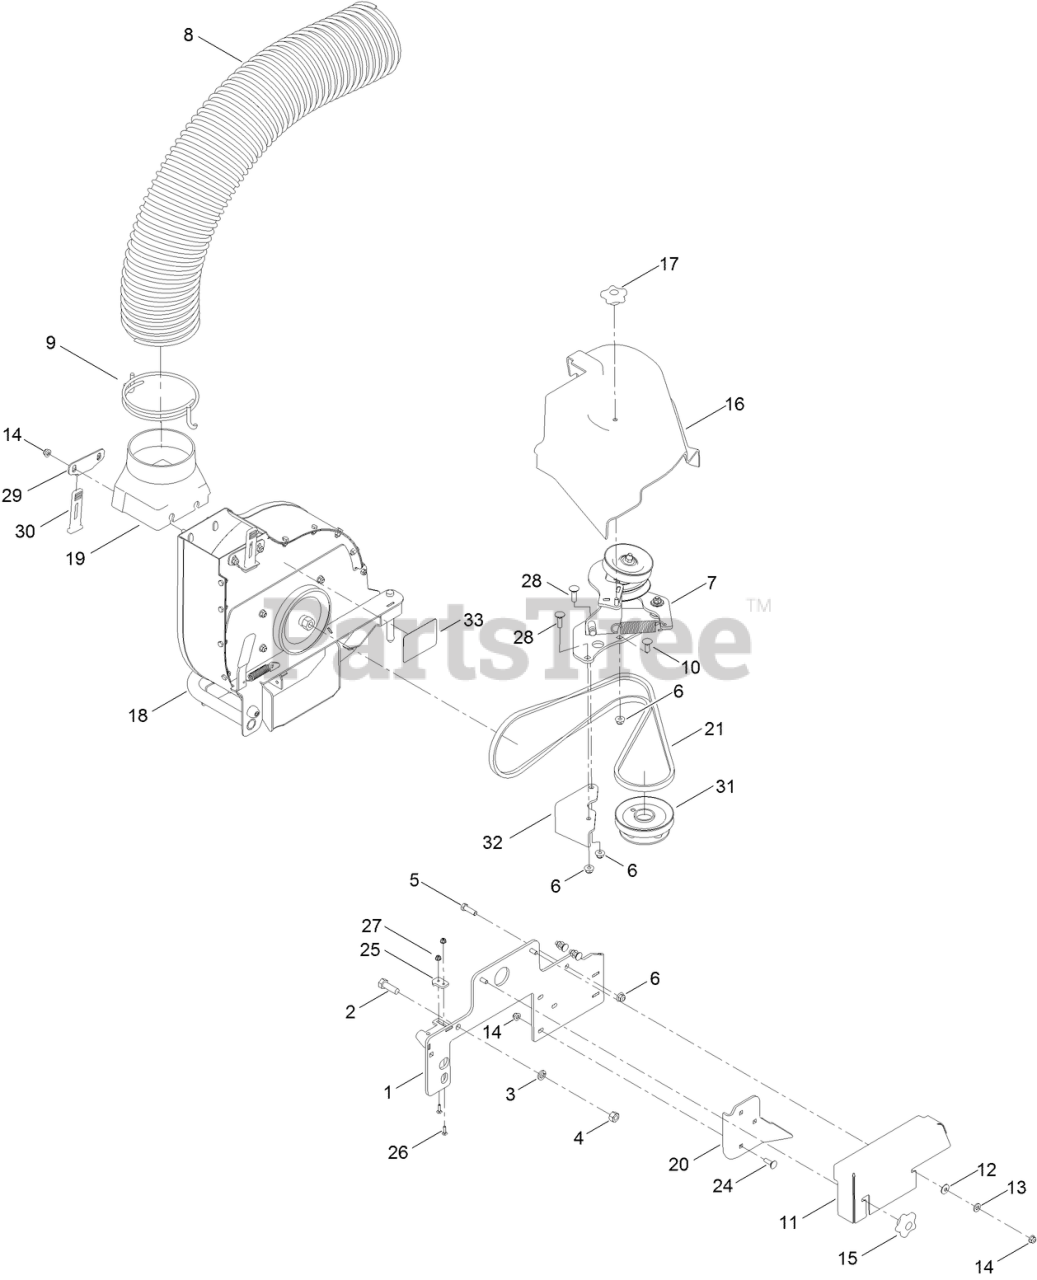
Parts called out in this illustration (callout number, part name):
1	BLOWER DECK MOUNT ASM
2	SCREW-HH
3	WASHER-LOCK
4	NUT-HH
5	SCREW-HH
6	NUT-HF, NI
7	IDLER ASM
8	HOSE-FLEXIBLE
9	CLAMP-HOSE, BAGGER
10	BOLT-CARR
11	GUARD-BELT, BLOWER
12	WASHER-BELLEVILLE
13	WASHER-RUBBER
14	NUT-HF, NI
15	KNOB-HANDLE
16	COVER-BELT
17	KNOB-HANDLE
18	BLOWER ASM
19	TRANSITION-BLOWER
21	BELT-V
24	BOLT-CARR
25	PLATE-LATCH
26	SCREW-CARR
27	NUT-HF
28	BOLT-CARR
30	STRAP-HOLD DOWN
31	BLOWER PULLEY ASM
32	BAFFLE-BAGGER, 60"
33	DECAL-ROUTING, BELT
